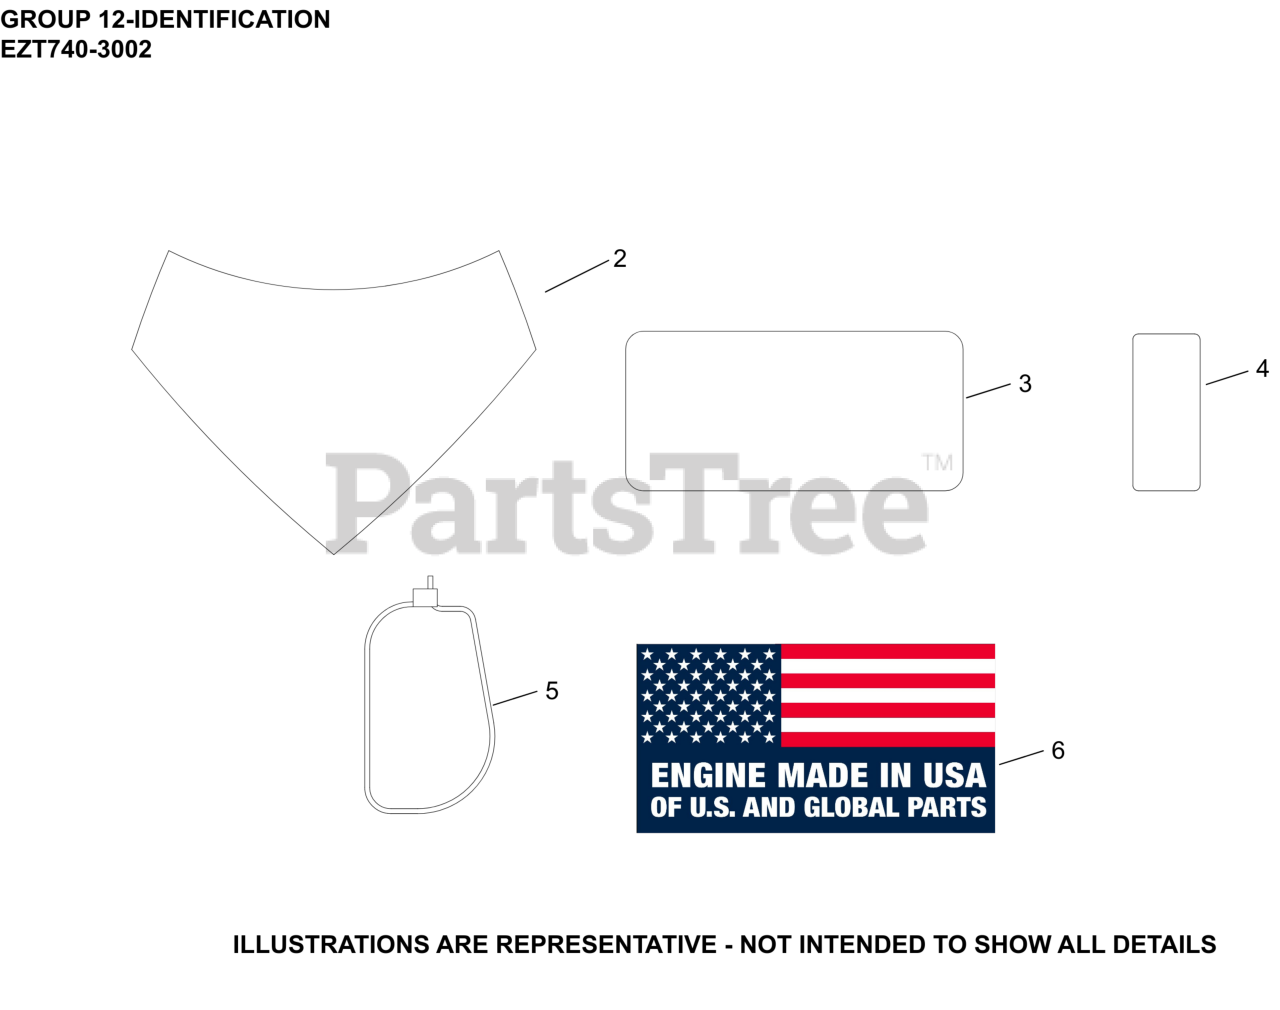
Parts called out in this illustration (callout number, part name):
2	LABEL, CONFIDANT (25HP, LPAC)
3	LABEL, CANADIAN COMPLIANCE
4	LABEL, CLEAR LAMINATION
6	DECAL, USA
